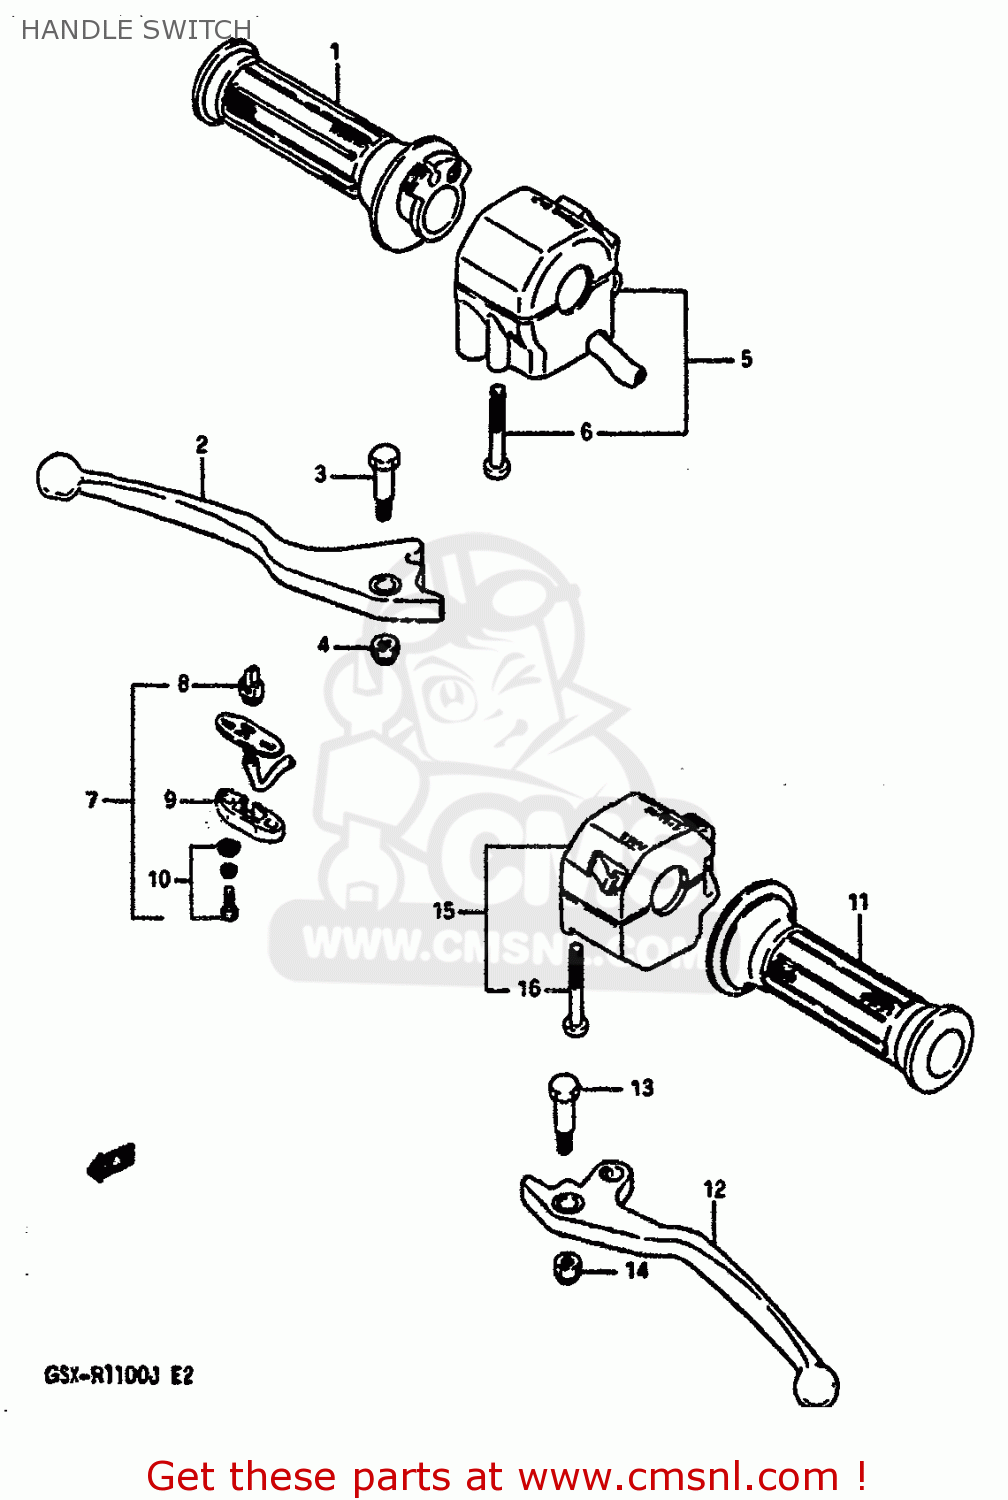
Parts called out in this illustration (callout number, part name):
1	GRIP,THROTTLE
2	LEVER,BRAKE
3	BOLT,LEVER
4	NUT
5	SWITCH ASSY,R
6	SCREW, 5X45
7	SWITCH ASSY,STOP
8	CONTACT,SWITCH
9	COVER,FR BK TERMINAL BASE
10	SCREW
11	GRIP,L
12	LEVER,CLUTCH (BLACK)
13	BOLT,LEVER
14	NUT
15	SWITCH ASSY, HANDLE LH
16	SCREW
